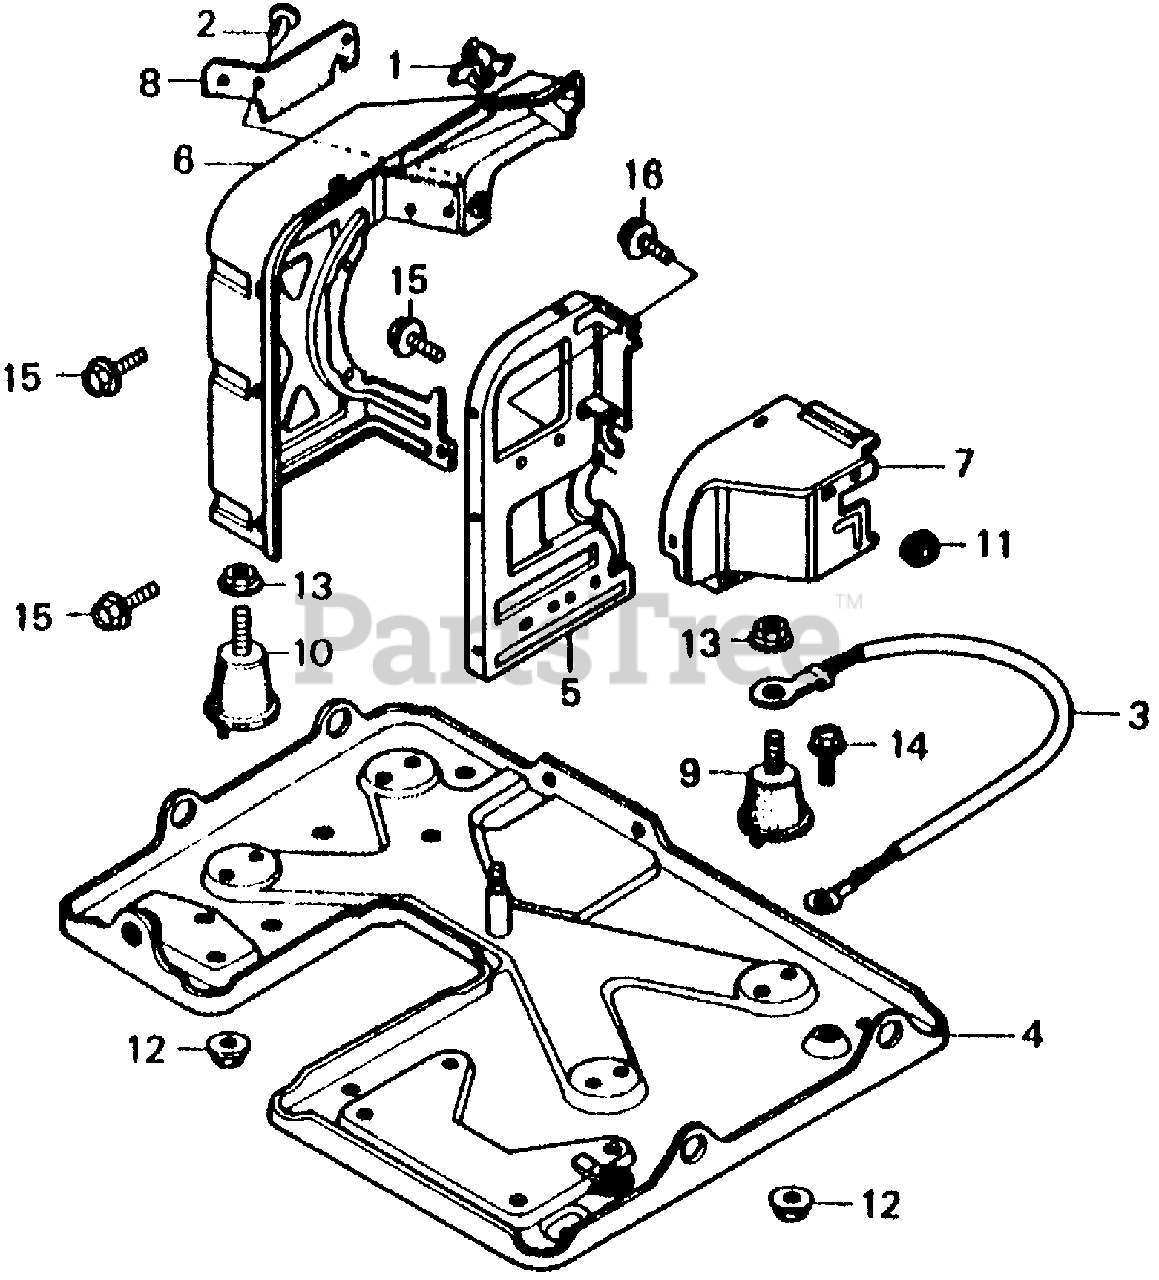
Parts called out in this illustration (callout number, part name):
1	CLIP, IGNITION WIRE (8MM)
2	CLIP, WIRE HARNESS BAND (NOT AVAILABLE)
3	CABLE, GROUND
4	BED, FRAME
5	BASE, HOT AIR *NH1* (BLACK)
6	COVER, HOT AIR *NH116M* (URBAN SILVER METALLIC)
7	GUIDE, HOT AIR *NH116M* (URBAN SILVER METALLIC)
8	SEAL, HOT AIR
9	RUBBER, ENGINE MOUNTING
9	RUBBER, ENGINE MOUNT
10	RUBBER, ALTERNATOR SETTING
11	GROMMET, AIR CLEANER HOUSING
12	NUT, FLANGE (8MM)
13	NUT, FLANGE (10MM)
14	BOLT, FLANGE (6X10)
15	BOLT, FLANGE (6X12)
16	BOLT, FLANGE (8X16)
